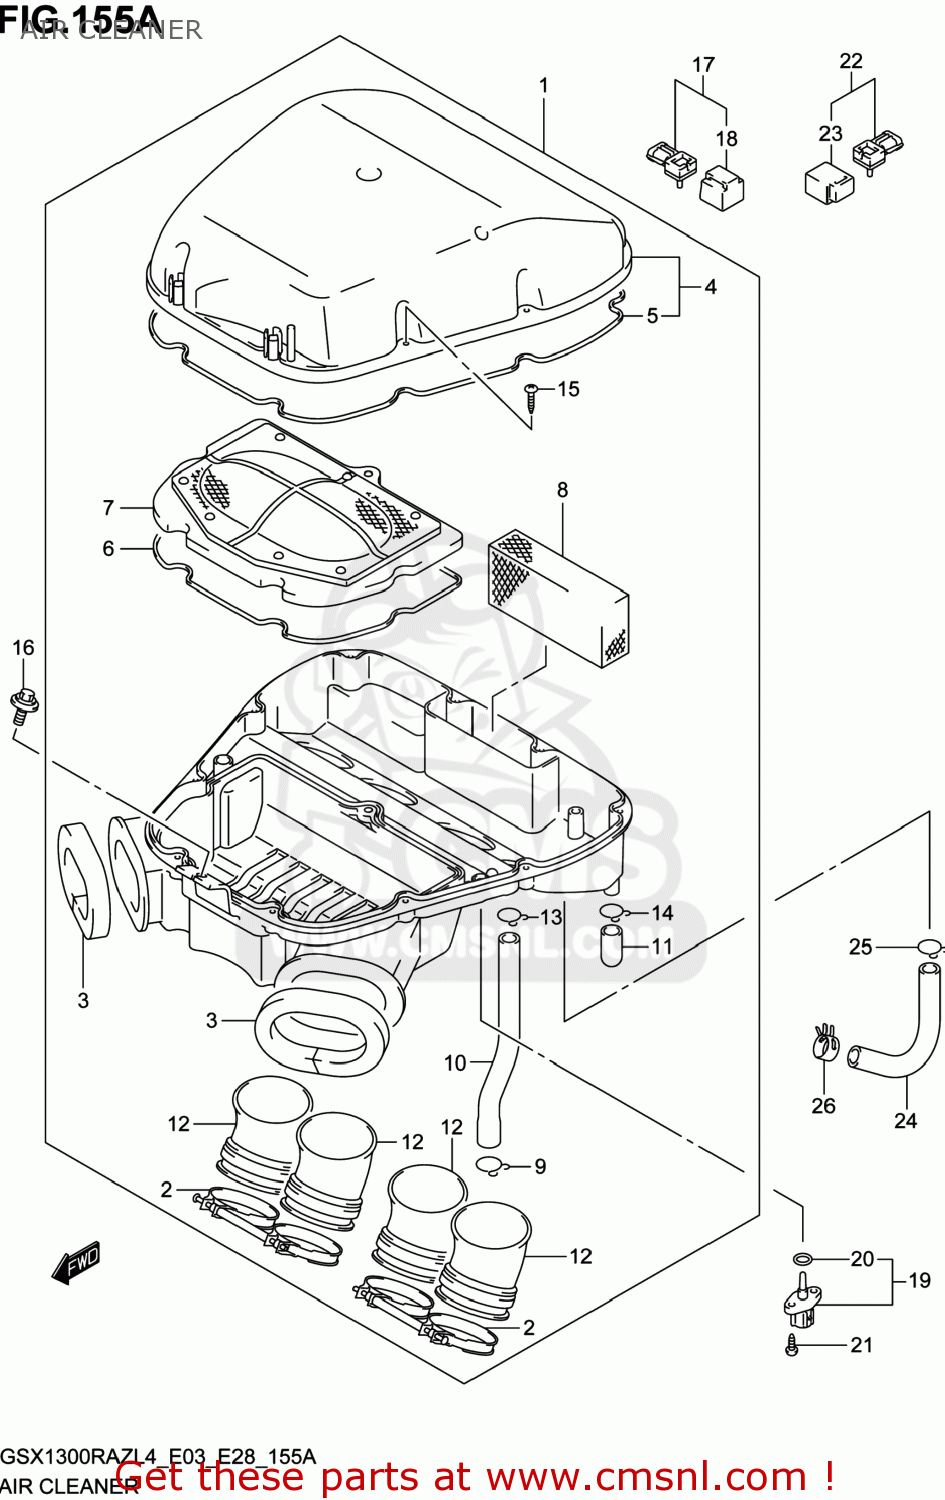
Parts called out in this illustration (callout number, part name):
1	CLEANER ASSY,AIR
2	CLAMP,INTAKE PIPE
3	CUSHION,DUCT
4	CAP,AIR CLEANER
5	GASKET,CAP (NAS)
6	GASKET,CASE (NAS)
7	FILTER ASSY
8	FILTER,BREATHER
9	CLIP
10	TUBE,BREATHER
11	PLUG
12	TUBE,OUTLET B
13	CLIP
14	CLIP
15	SCREW
16	BOLT(6X16)
17	SENSOR,BOOST
18	COVER
19	SENSOR,AIR TEMP
20	O RING
21	SCREW
22	SENSOR,AIR PRESSURE
23	COVER
24	HOSE,ISC VALVE
25	CLIP
26	CLIP
